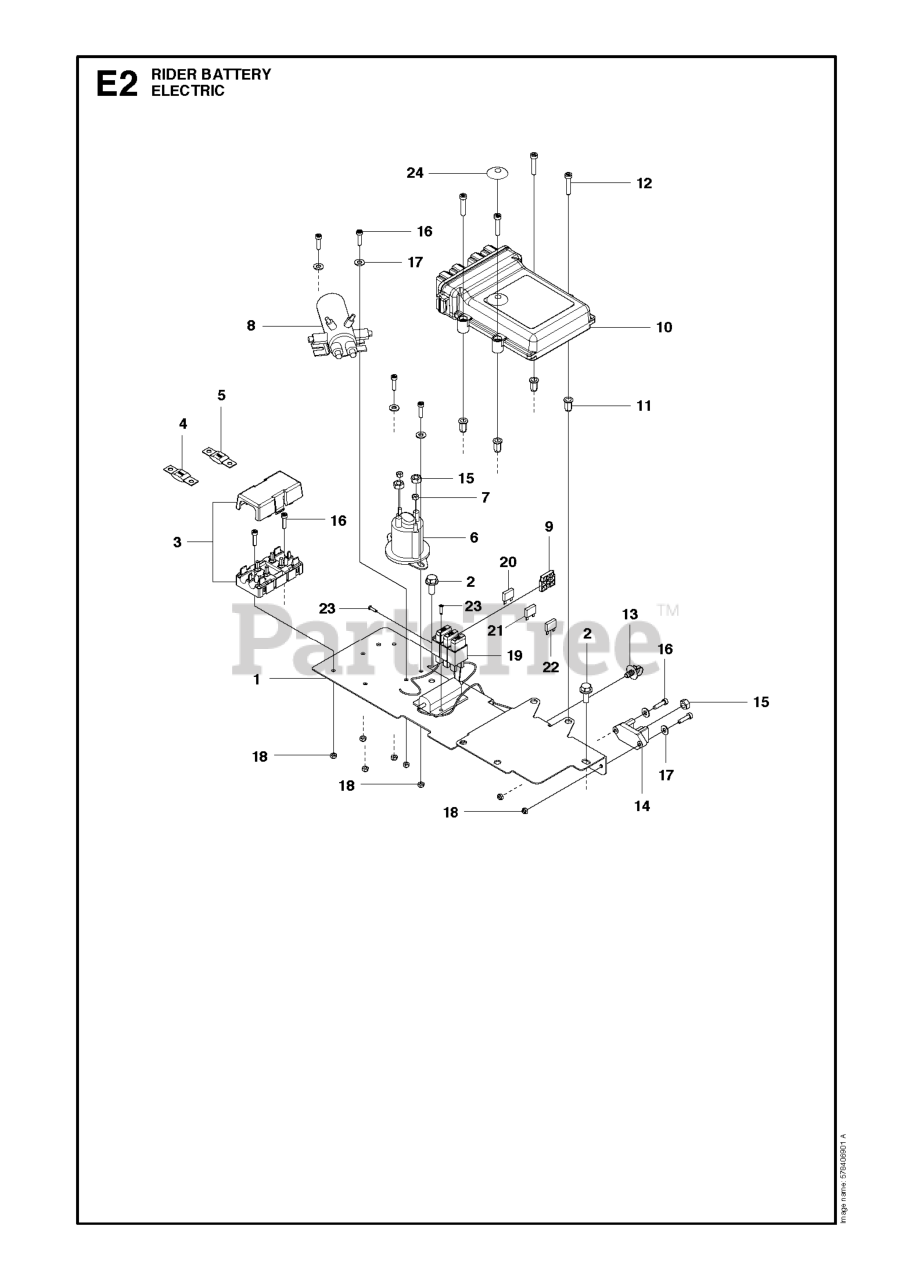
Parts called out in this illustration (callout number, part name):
12	SCREW ITXSCM M6X30 T27 10.9 Z
15	NUT
16	SCREW ITSXCM
17	WASHER
18	LOCKNUT M5
